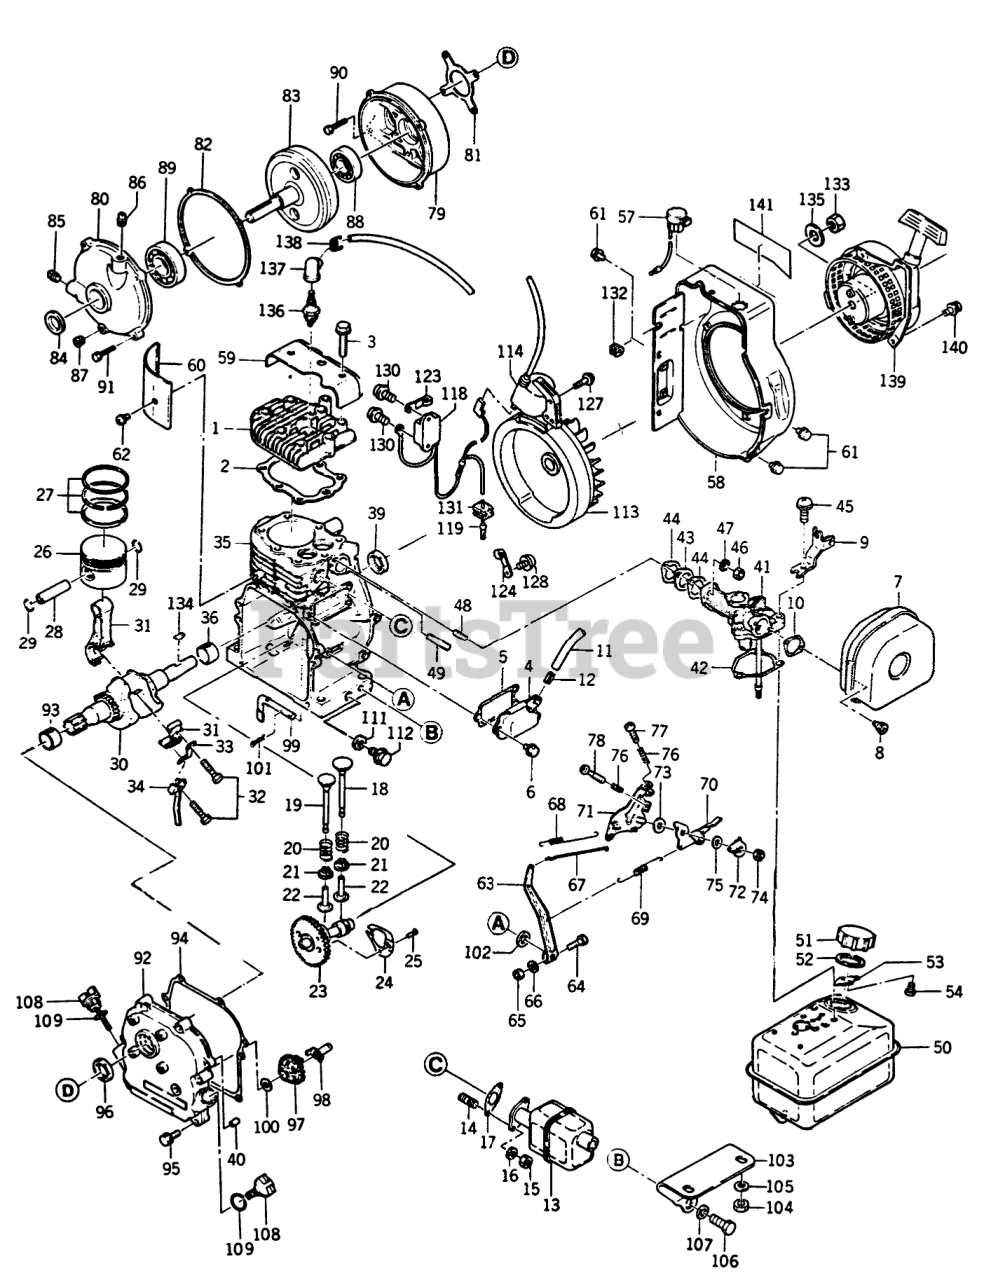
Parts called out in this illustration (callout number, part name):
1	CYLINDER HEAD
2	GASKET
3	BOLT (8X50)
4	VALVE CHAMBER COVER
5	GASKET
6	BOLT (6X12)
7	Air Cleaner Complete (see SECTION 1-3 for complete parts breakdown)
9	AIR CLEANER STAY
10	GASKET
11	RUBBER TUBE
13	MUFFLER
14	Stud
15	NUT 6MM
16	WASHER-PLAIN 6MM
17	GASKET
18	INTAKE VALVE
19	EXHAUST VALVE
20	VALVE SPRING
21	SPRING SEAT
22	TAPPET
23	Cam Shaft Complete (includes items 24 & 25)
24	DECOMPRESSOR
26	PISTON (STD)
26	PISTON 0.25MM O/S
26	PISTON 0.50MM O/S
27	RING SET (STD)
27	RING SET 0.25MM O/S
27	RING SET 0.50MM 0/S
28	PISTON PIN
29	SNAP RING
30	CRANK SHAFT
31	Connecting Rod (includes item 32)
32	CONNECTING ROD BOLT
33	LOCKWASHER
34	SPLASHER ARM
35	Crank Case (includes item 36)
36	GASKET
39	Oil Seal
40	Dowel Pin
41	CARBURETOR ASS'Y
42	GASKET
43	INSULATOR
44	GASKET
45	SCREW (6X25)
46	NUT 6MM
47	WASHER-PLAIN 6MM
50	Fuel Tank Assy (includes items 51, 52, 53 & 54)
51	Tank Cap Assy (includes items 52, 53 & 54)
52	GASKET
53	SPRING
54	SCREW
57	STOP SWITCH
58	FAN HOUSING
59	CYLINDER HEAD COVER
60	CYLINDER COVER
61	BOLT (6X10)
62	SCREW (5X10)
63	GOVERNOR ARM ASS'Y
65	NUT 6MM
66	Washer
67	GOVERNOR LINK
68	Link Spring
69	SPRING
70	CONTROL LEVER
71	BRACKET
72	BRACKET
73	WASHER
75	SPRING
76	SPRING
77	SCREW (4X20)
78	SCREW (4X25)
81	GASKET
82	GASKET
83	SHAFT
84	OIL SEAL
88	Ball Bearing
89	BALL BEARING
90	BOLT (8X30)
91	BOLT (6X25)
92	SIDE BASE
93	PLAIN BEARING
94	GASKET
95	BOLT (6X28)
96	Oil Seal
97	GOVERNOR ASS'Y
98	GOVERNOR SLEEVE
99	GOVERNOR TIP
101	Pin
102	Washer
103	TANK BRACKET
105	WASHER
106	BOLT (8X16)
107	WASHER
108	OIL GAUGE
109	O-Ring
111	GASKET
112	BOLT (10X14)
113	FLYWHEEL
114	IGNITION COIL
118	IGNITER
119	LEAD WIRE
123	CLAMP
124	CLAMP
127	BOLT (5X20)
128	SCREW (4X8)
130	SCREW (5X14)
131	GROMMET
132	GROMMET
133	Nut 14mm
135	WASHER
136	OBS SPARK PLUG
137	Plug Cap
138	SPRING
139	Recoil Starter Assy (see SECTION 1-4 for complete parts breakdown)
140	BOLT (6X10)
141	DECAL
